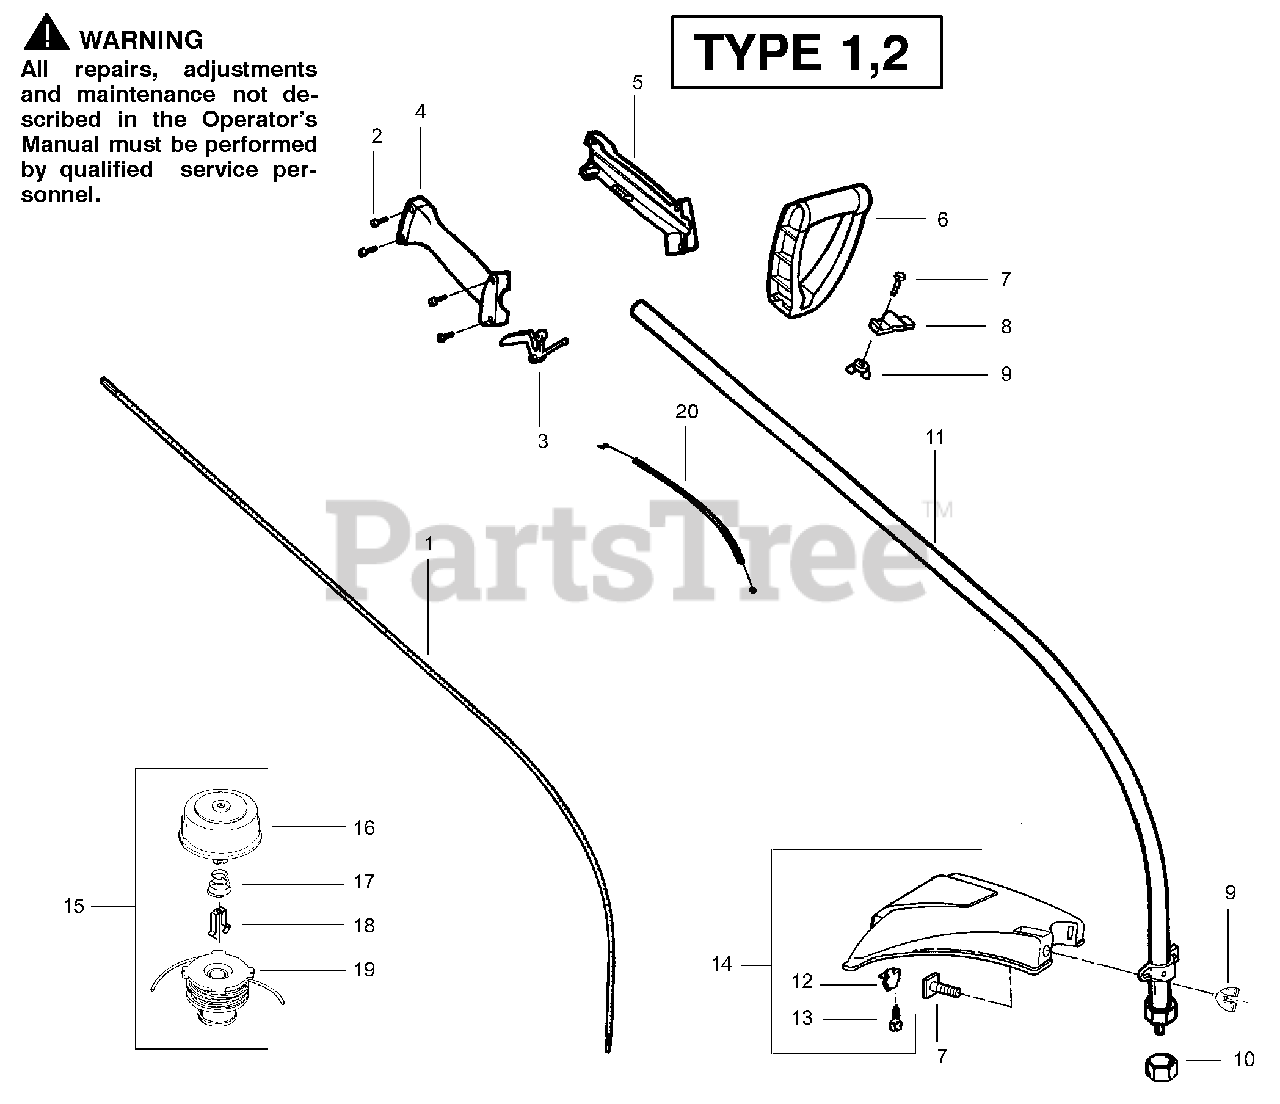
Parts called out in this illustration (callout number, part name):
1	Drive Shaft- Flex
2	Screw-Throttle Hsg.
4	Throttle Hsg. (Right)
5	Throttle Hsg. (Left)
6	Handle
7	Bolt-Handle/Shield
8	Clamp-Assist Handle
9	Wingnut
10	Dust Cup
11	Drive Shaft Hsg. Ass'y.
12	Line Limiter
13	Screw-Line Limiter
14	Shield Kit Ass'y.
15	Cutting Head Ass'y.
16	Hub Ass'y.
17	Spring-Return
18	Retainer-Spool
19	Spool w/Line
20	Assy-Throttle Cable
